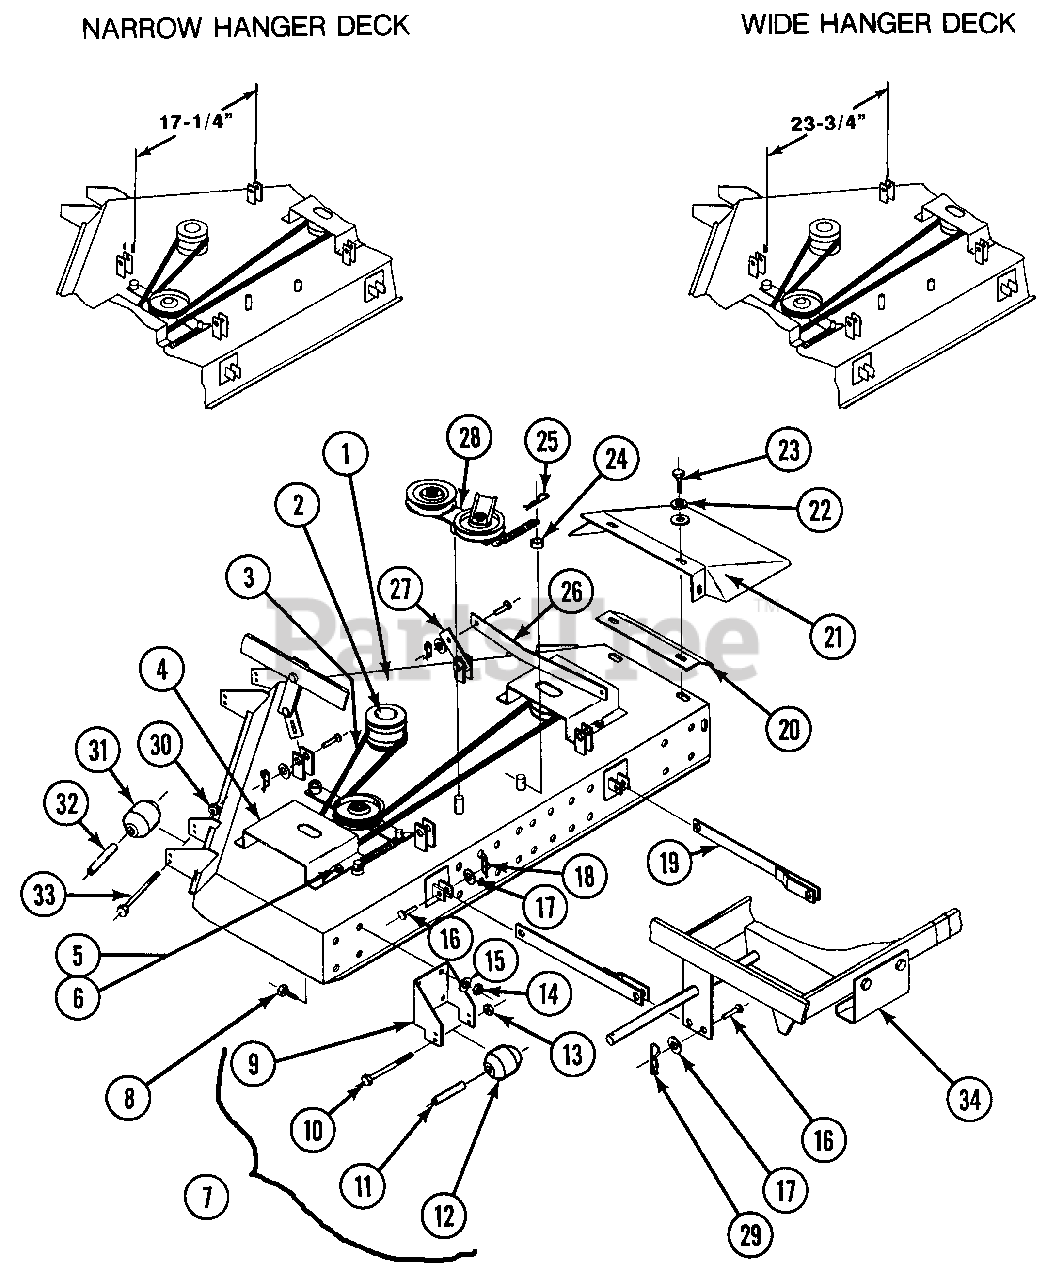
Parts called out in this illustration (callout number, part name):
1	DECK WELDMENT, 42"
1	DECK WELDMENT, 42" WIDE HANGER
1	DECK WELDMENT, 48"
1	DECK WELDMENT, 48" WIDE HANGER
2	SPINDLE ASSEMBLY
3	BELT, L496, 42" DECK
3	BELTS AP105, 48" DECK
4	PULLEY COVER
5	LOCKWASHER, 1/4 STD, SPLIT SPRING
6	CAPSCREW, HEX, 1/4-20 X 3/4, GRADE 5
7	SINGLE IDLER ASSEMBLY
8	CAPSCREW, HEX, 3/8-16 X 7/8, GRADE 5
8	ANTISCALPER ROLLER ASSEMBLY
9	REAR SCALPER BRACKET
10	CAPSCREW, HEX, 3/8-16 X 4-1/2, GRADE 5
11	ROLLER SPACER BUSHING
12	ANTISCALPER ROLLER
13	LOCKNUT, HEX, 3/8-16 UNC
14	LOCKNUT, HEX, 3/8-16 W/ NYLOC
15	WASHER, 3/8 FLAT, W SERIES
16	PIN, CLEVIS, 5/16 X l-1/4
17	WASHER 5/16 FLATS STD
18	COTTER, RUE RING, 5/16 - 3/8 PIN
19	LINKAGE BAR 42" & 48" STANDARD DECK
20	CHUTE DEFLECTOR 42" DECK
20	CHUTE DEFLECTOR 480 DECK
21	GRASS CHUTE ASSEMBLY 42" DECK
21	GRASS CHUTE ASSEMBLY 48" DECK
22	LOCKWASHER, 5/16 HEAVY, SPLIT SPRING
23	CAPSCREW, HEX, 5/16-18 X 3/4, GRADE 5
24	SPRING SPACER
25	PIN, HAIR SPRINGER 1/8 X 2-1/2
26	DECK CONNECTOR BAR
27	DECK ADJUSTMENT BAR
28	DOUBLE IDLER ASSEMBLY
29	PIN, HAIR SPRINGER .080 X 1-9/16
30	LOCKNUT, HEX, 3/8-16 W/NYLOC
31	ANTISCALPER ROLLER
32	ROLLER SPACER BUSHING
33	CAPSCREW, HEX, 3/8-16 X 4-1/2, GRADE 5
34	CLUTCH STOP GUARD
